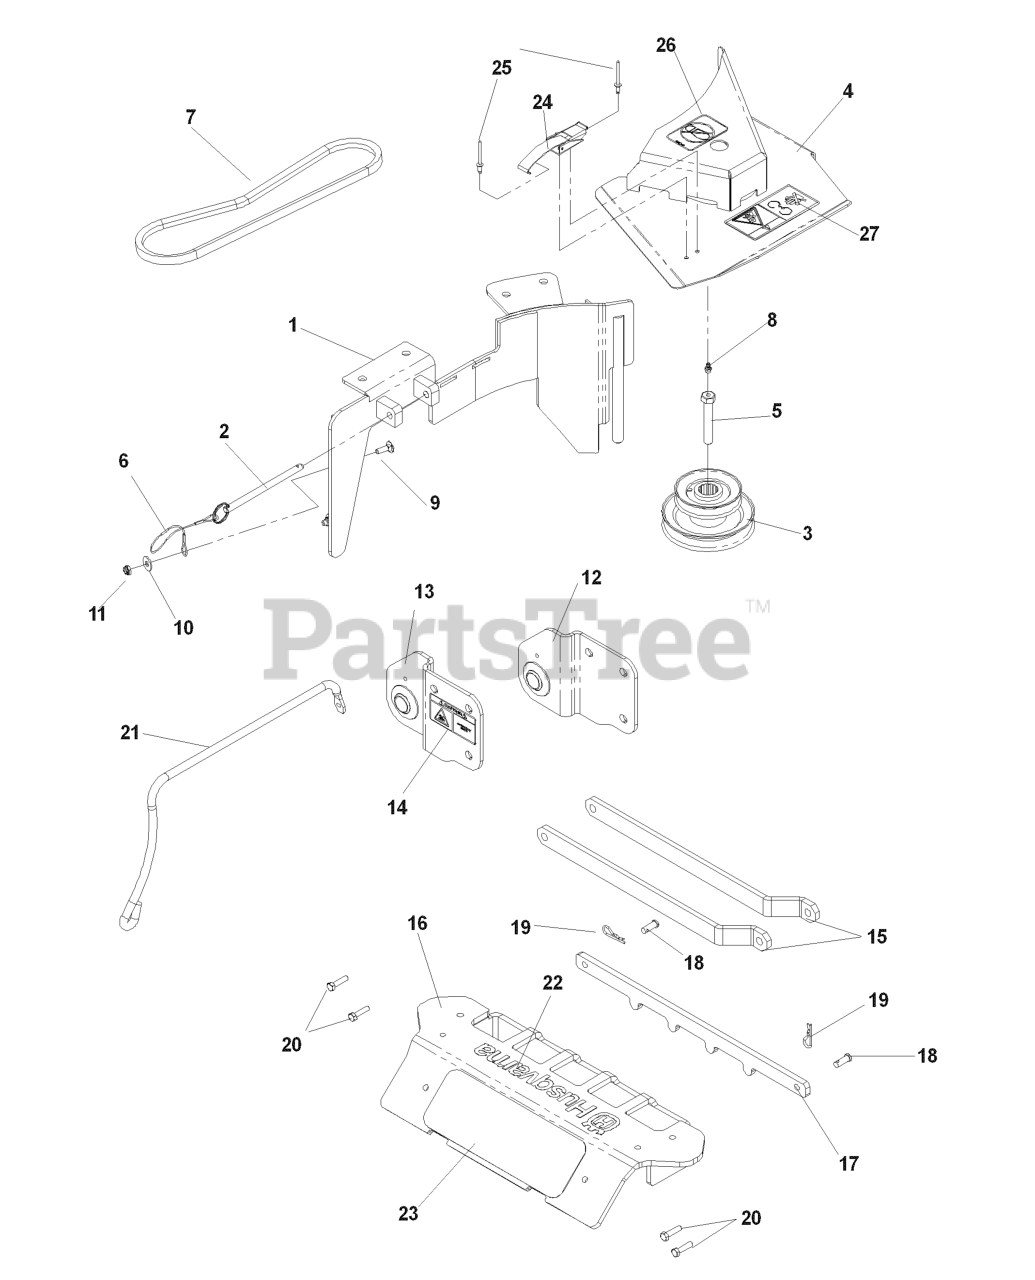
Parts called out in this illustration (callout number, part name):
1	BLOWER DECK PLATE
3	42/48 LG DBL HEX STACK PULLEY
4	BELT SHIELD ASSY 48"
5	HCS, 7/16-20 X 2 1/2, GR8
8	ZERK
9	RHSNB 1/4C X 3/4
10	WASHER 1/4 FLAT
11	JAM NUT 1/4C (2 2 PW01)
12	HITCH BRACKET WLD
13	HITCH BRACKET WLDMT, RT, MID
14	DECAL, HOT SURFACE
16	WEIGHT BAR, IZ
17	HOLD DOWN, WEIGHT BAR
18	CLEVIS PIN
19	RETAINER SPRING
20	HCS 5/16C X 1 1/4
21	HOSE SUPPORT
22	DECAL, HUSQ 12" BLUE
23	ANTI-SKID PAD
24	DRAW LATCH
25	RIVET, BLIND, 5/32 DIA
26	DECAL, NO STEP
27	DECAL, BELT DRIVE
